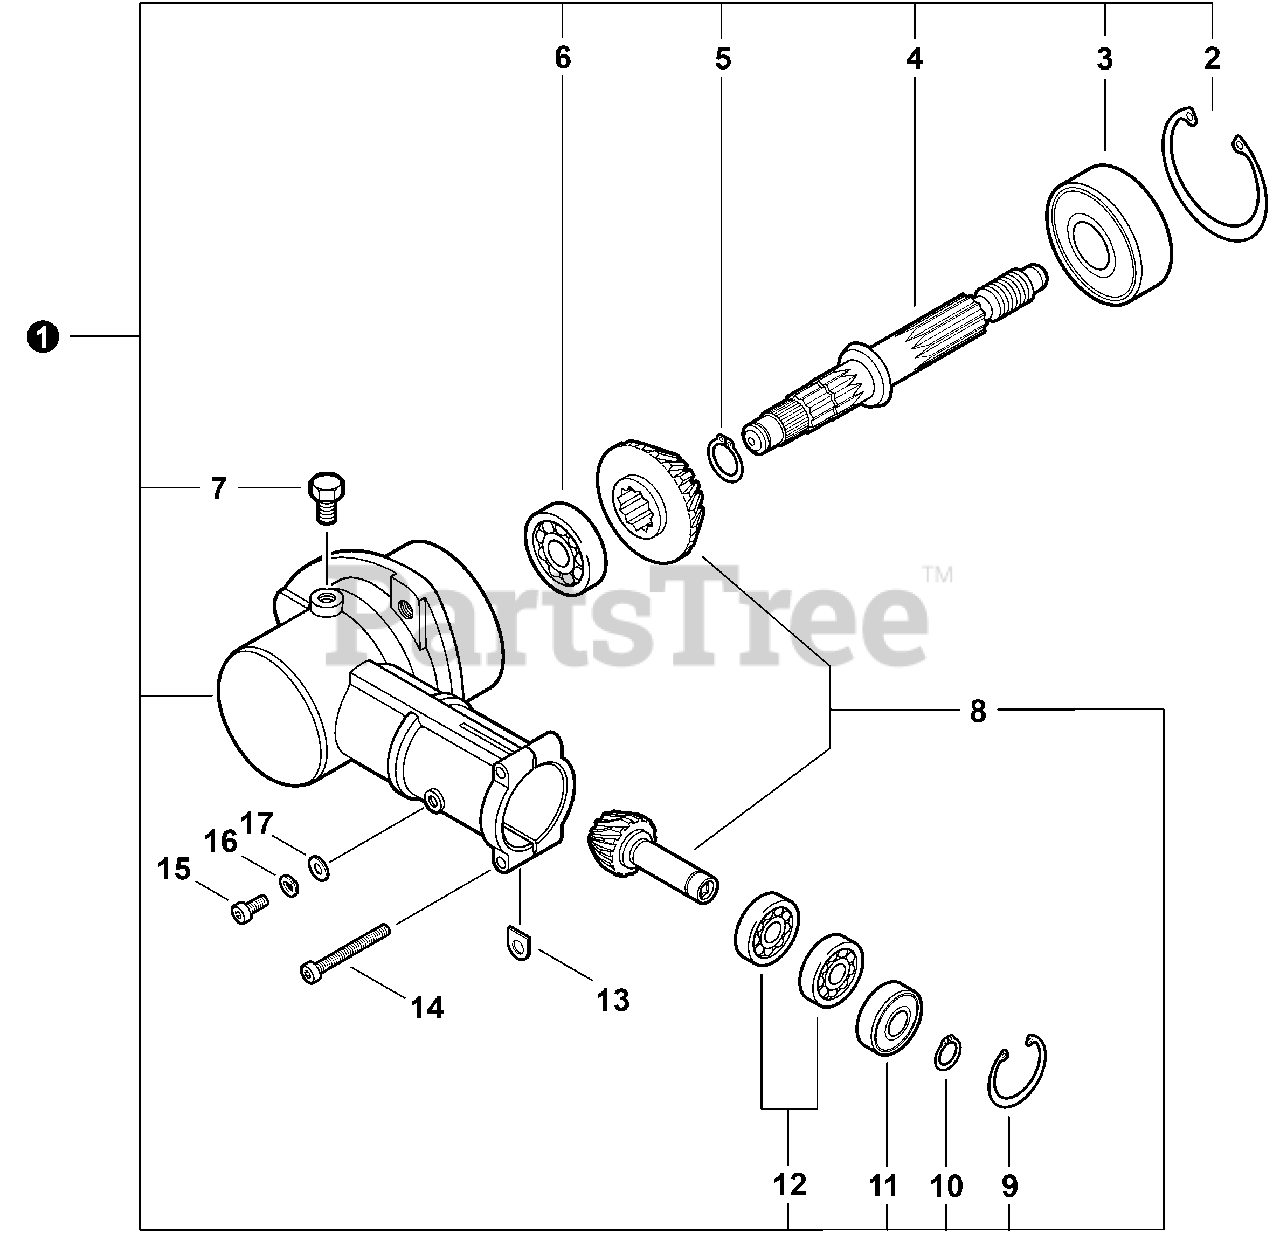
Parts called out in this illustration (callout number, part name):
1	GEAR CASE ASY
2	RING, RETAINING - 42
3	BEARING, BALL 609
4	GEAR, SHAFT
5	RING, RETAINING - 12
6	BEARING, BALL - 629
7	BOLT 8×8
8	GEAR SET
9	RING, RETAINING - 22
10	RING, RETAINING - 10
11	BEARING, BALL - 6900Z
12	BEARING, BALL - 6900
13	WASHER, SHIM
14	SCREW - 5×25
15	SCREW - 5×12
16	LOCKWASHER - 5
